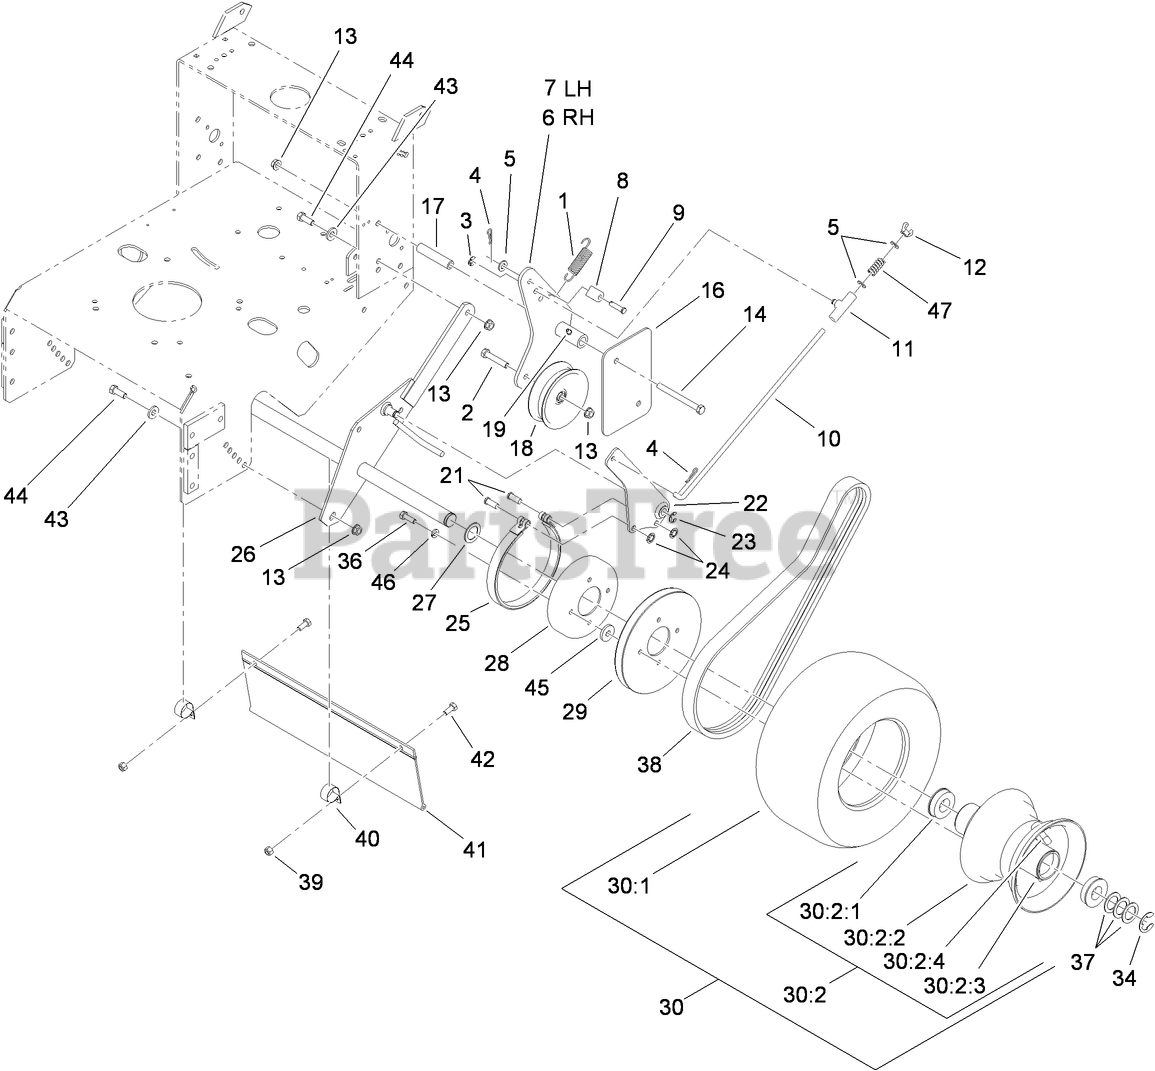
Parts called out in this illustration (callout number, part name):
1	SPRING-EXTENSION
2	SCREW-HH
3	RING-RETAINING
4	PIN-COTTER
5	WASHER-PLAIN
6	ARM-IDLER, RH
7	ARM-IDLER, LH
8	FITTING-ROD
9	PIN-CLEVIS
10	ROD-BRAKE
11	SWIVEL-BRAKE
12	WINGNUT-NYLOCK
13	NUT-HHF, WHIZ
14	SCREW-HH
16	SHIELD-WHEEL, DRIVE
17	SPACER-SHIELD
18	IDLER-DRIVE, WHEEL
19	FITTING-GREASE
21	PIN-CLEVIS
22	ARM-BRAKE
23	RING-RETAINING, EXTERNAL
24	NUT-PUSH
25	BAND-BRAKE
26	AXLE ASM
27	WASHER-SPACER
28	DRUM-BRAKE
29	SHEAVE-WHEEL, DRIVE
30	Wheel AND Tire ASM
30:2	WHEEL AND HUB ASM
30:2:1	BEARING-FLANGED
30:2:2	Rim ASM
30:2:3	Fitting-Grease
30:2:4	Valve Stem and Cap
34	RING-SNAP
36	SCREW-HH
37	WASHER-SPACER
38	BELT-DRIVE, WHEEL
39	NUT-LOCK, NI
40	CLAMP-R
41	SHIELD-TRAILING
42	SCREW-HH
43	WASHER-BELLEVILLE
44	SCREW-HH
45	WASHER
46	WASHER-LOCK
47	SPRING-COMPRESSION
